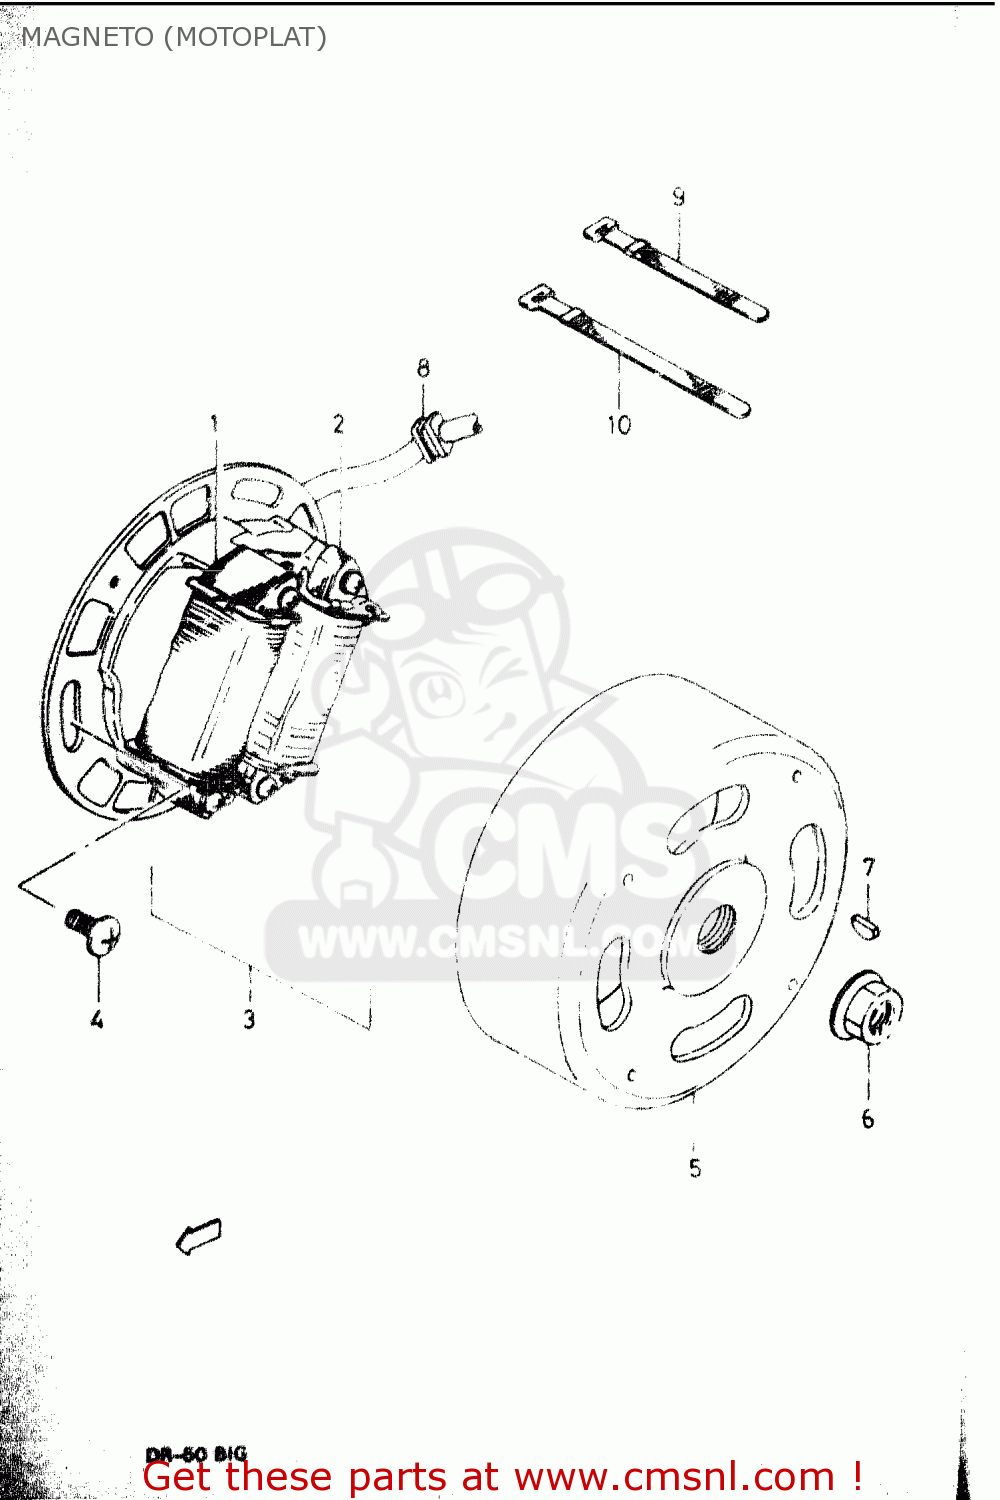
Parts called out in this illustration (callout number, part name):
1	COIL, LIGHTING
2	COIL, PRIMARY
3	STATOR ASSY
4	SCREW
5	ROTOR
6	NUT
7	KEY
8	CUSHION
9	CLAMP L=138
10	CLAMP L=170
